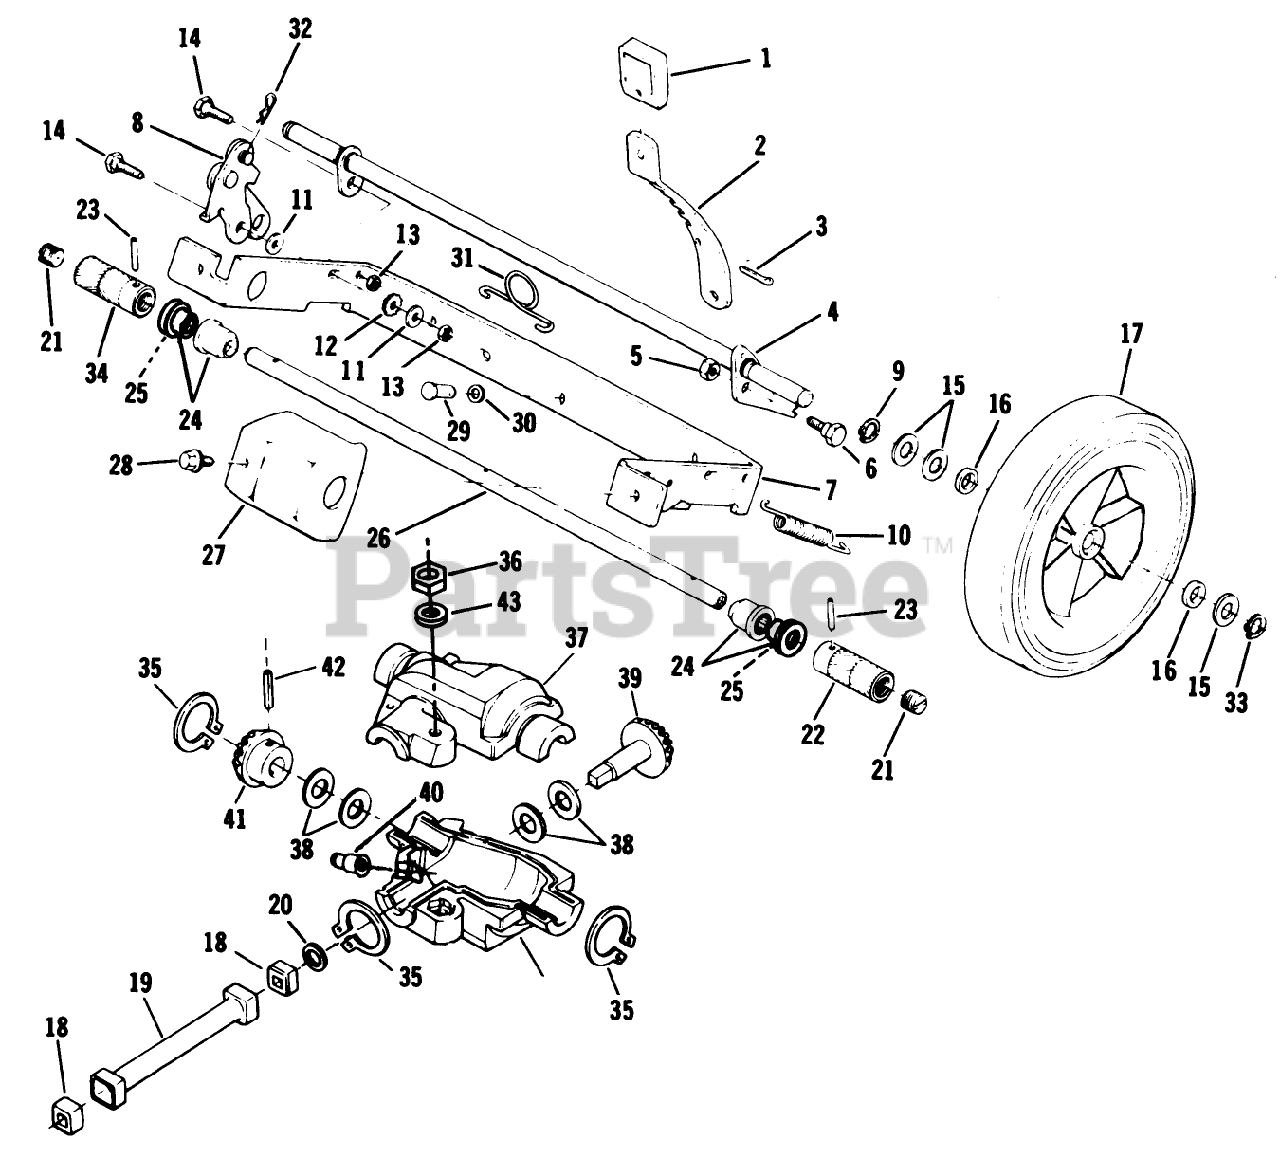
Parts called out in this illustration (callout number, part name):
1	KNOB
2	LEVER
5	LOCKNUT E
6	BOLT RB&W
7	BRK-21" AXLE
9	RET RING
10	SPRING
11	WASHER S
13	STOP NUT
14	BOLT RB&W
15	SPACER
16	WASHER
17	WHEEL & TIRE KIT
18	BUSHING
20	O-RING
21	GREASE PLUG
22	ROLLER (LEFT) VS
22	ROLLER-LH
24	SLEEVE &BEARING AY
25	P/M Bearing
26	DRIVE SHFT TAG AY
27	GUARD
29	PIN
30	WASHER SPRING LAR
31	SPRING N.A.S
33	RET RING
34	ROLLER (RIGHT) VS
34	ROLLER-RH
36	LOCKNUT E
37	GEARCASE AY-SERV
38	THRUST WASHER
39	GEAR BEST
40	ZERK FITTING
41	GEAR ADVANCE
42	ROLL PIN
43	WASHER F
